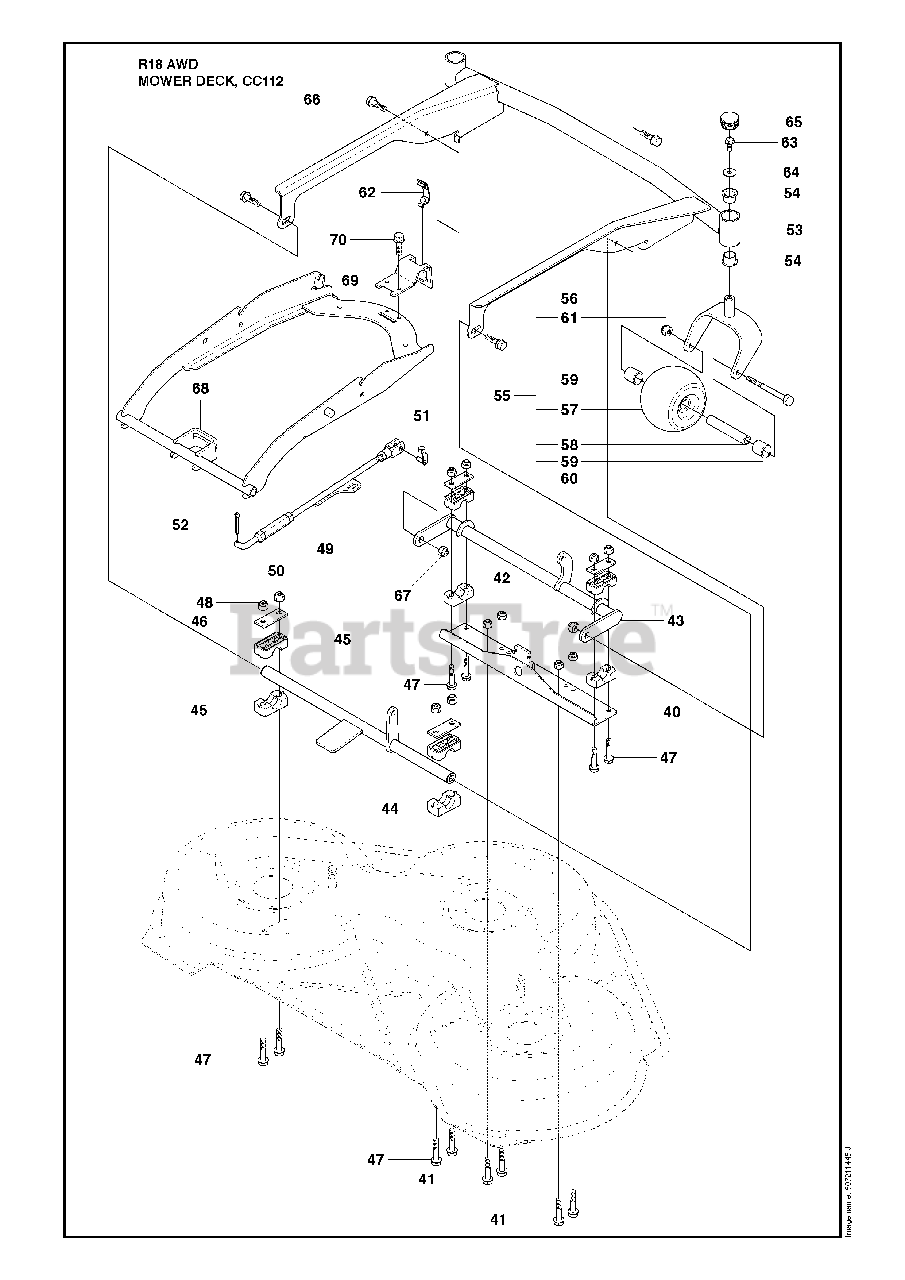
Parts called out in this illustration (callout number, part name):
1	CUTTING DECK
5	SPINDLE ASSY
6	BEARING HOUSING
10	RP SPINDLE ASSY
11	BEARING HOUSING
16	WASHER BRB 8.4X17
17	LOCKNUT M8
24	BLADE
25	WASHER
27	BELT TENSIONER ASSY
28	BELT TENSIONING ARM
32	WASHER
34	LOCKNUT M8
36	BELT
37	BELT COVER
42	LOCKNUT M8
48	LOCKNUT M8
49	PARALLELL ROD ASSY
50	PARALLEL ROD
51	RETAINER
53	DECK FRAME
55	PIVOT WHEEL ASSY
57	DECK ROLLER, FRONT
61	NUT
62	CLIP GRAY
66	Screw
67	LOCKNUT M8
68	DECK ATTACHMENT
70	Screw
